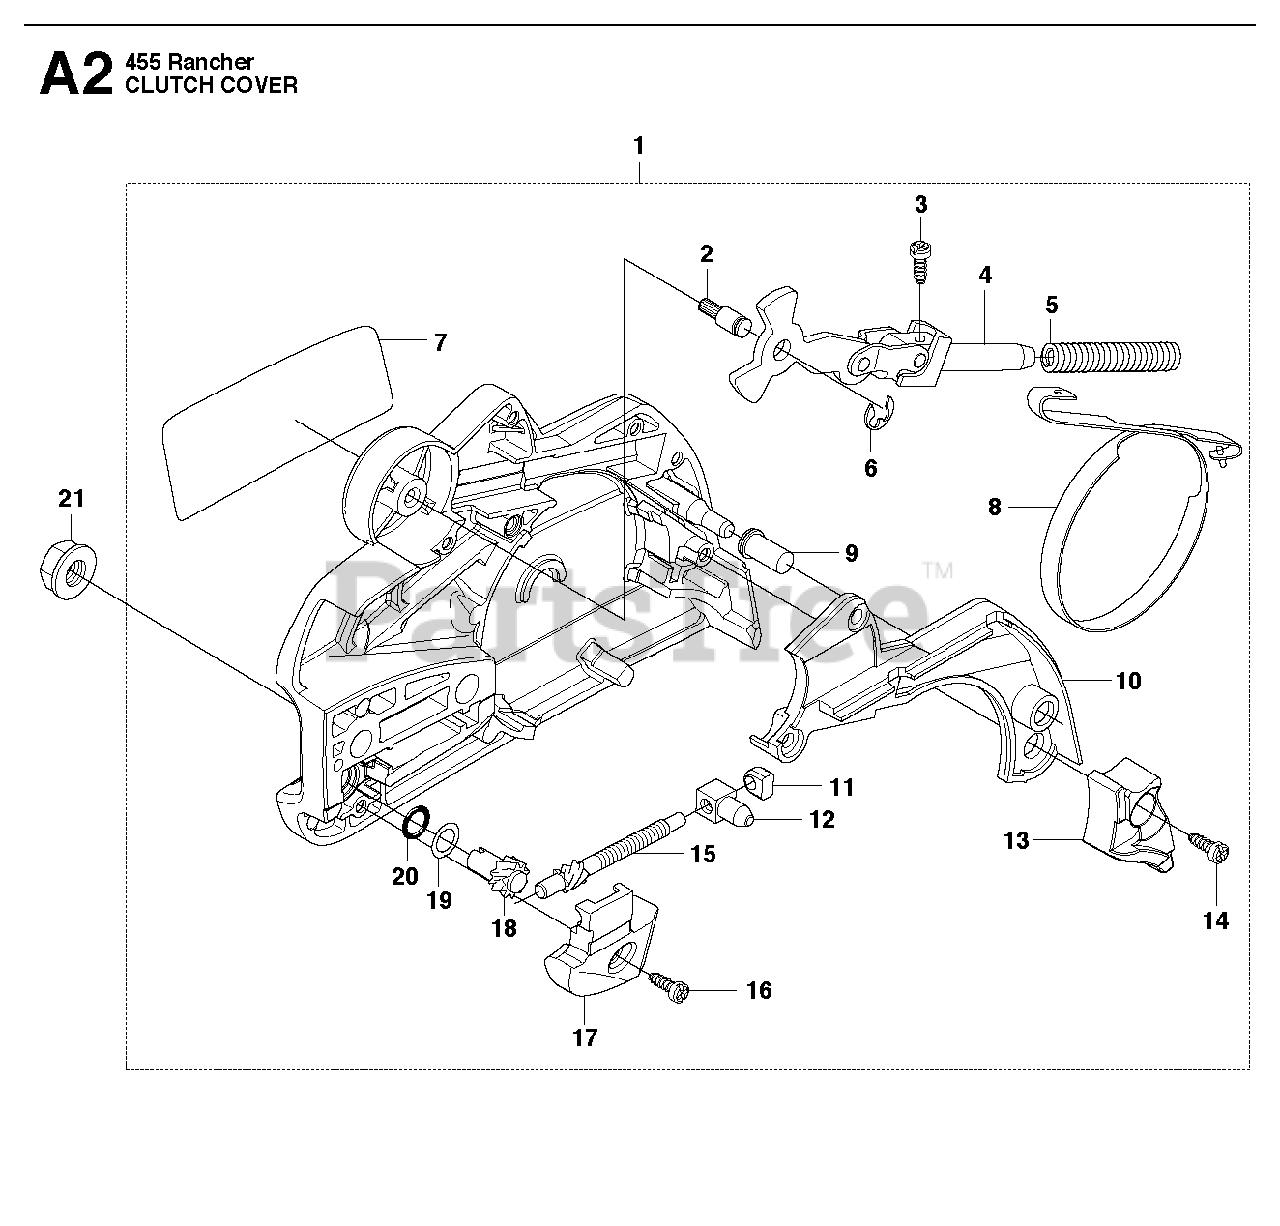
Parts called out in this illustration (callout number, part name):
1	CLUTCH COVER
2	PIN
3	SCREW
4	JOINT
5	SPRING
6	E-RING 4
7	DECAL, CLUTCH COVER
8	BRAKE BAND
9	SLEEVE
10	COVER
11	SLEEVE
12	PAWL
13	PROTECTOR
14	SCREW
15	SCREW
16	SCREW
17	COVER
18	WORM WHEEL
19	WASHER
20	O-RING
21	NUT M8 FLANGE
